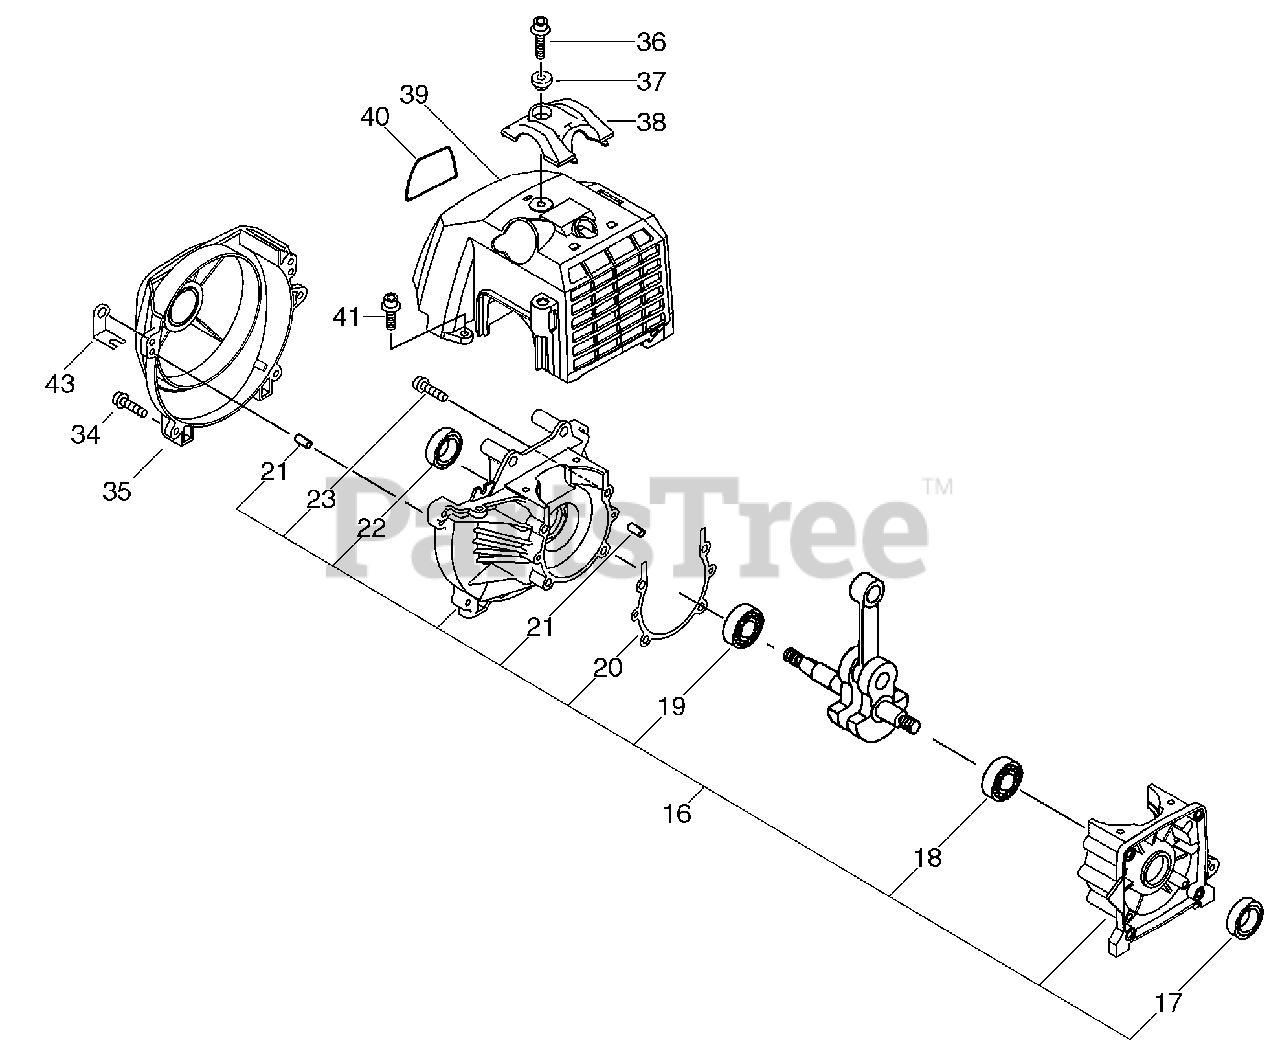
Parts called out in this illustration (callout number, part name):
16	CRANKCASE KIT
17	SEAL, OIL
18	BEARING, BALL - 6201
19	BEARING, BALL - 6202
20	GASKET, CRANKCASE
21	PIN - LOCATING
22	SEAL, OIL
23	SCREW - 5X35
34	SCREW - 5X20
35	COVER, FAN
36	SCREW - 5X20
37	COLLAR - 5
38	GUARD - TOP
39	COVER, ENGINE - ORANGE
40	LABEL - MODEL SRM-4300
41	SCREW - 5X12
43	HOLDER, CABLE
